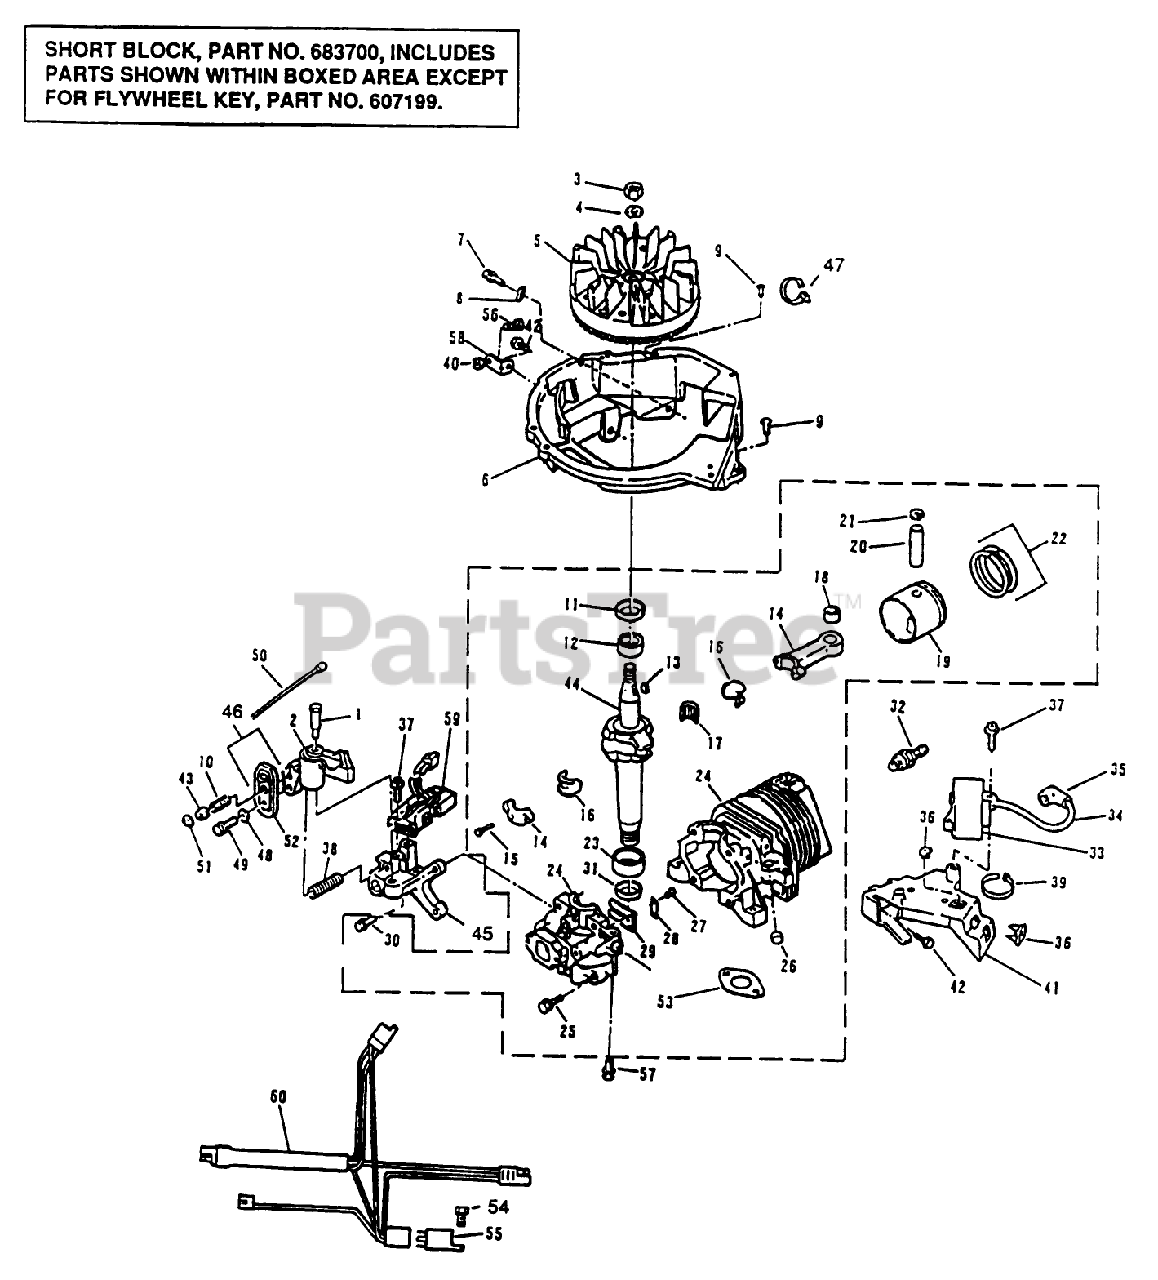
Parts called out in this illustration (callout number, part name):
1	SCREW-SHOULDER
3	NUT
5	FLYWHEEL ASSY F
6	BASE SHROUD F
7	SCREW-SEMS
9	SCREW F
10	SPRING
11	SEAL-OIL
12	BEARING V
13	KEY
15	SCREW-HSH
16	LINER ASM
17	BEARING-NEEDLE
18	BEARING AY F
21	RING-RETAINING
23	BEARING V
25	SCREW-H.W.HD. F
26	PLUG-CORE VF
27	SCREW-HH
28	PLATE-BACKUP, REED
30	SCREW
31	SEAL-OIL
32	SPARK PLUG
34	HT LEAD&COVER XEV
35	COVER & TERM. AY S
36	NUT-CLIP
38	SPRING-BRAKE
39	TIE-CABLE
40	NUT-LOCK F
41	C.D. BRKT F
42	SCREW F
43	ACTUATOR-LEVER, BRAKE
45	BRACKET F
50	WIRE LEAD AY F
51	RETAINER S
54	SCREW F
56	BOLT F
59	ALTERNATOR AY F
